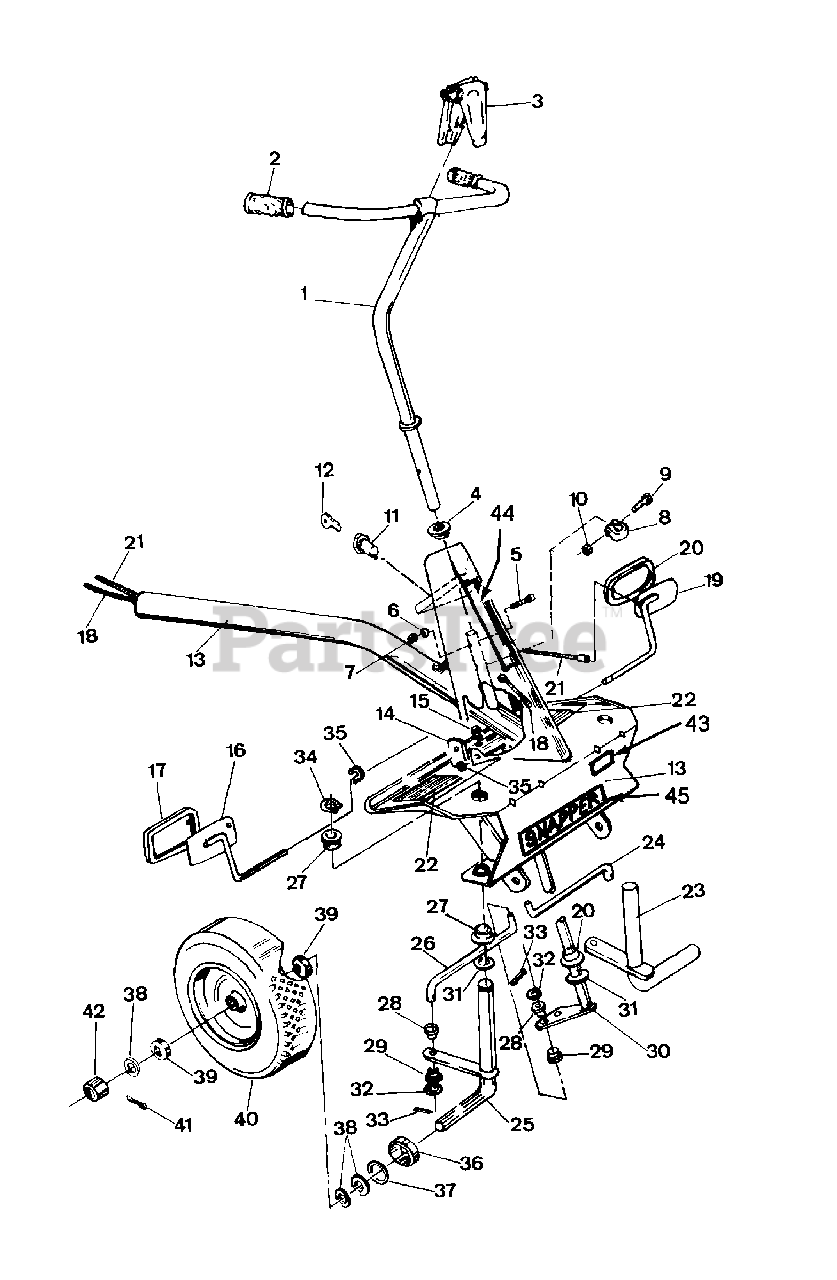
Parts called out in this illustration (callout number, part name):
1	HANDLE, Steering
2	GRIP, Steering Handle
3	COVER, Handle Center
4	BUSHING, Nylon
5	BOLT, Tapered Head
6	LOCKWASHER, 1/4 Int. Tooth
7	NUT, 1/4-28 Hex
8	CLAMP, (Handle Retaining)
9	CARRIAGE BOLT, 5/16-18 x 1-1/2"
10	NUT, 5/16-18 Hex
11	SWITCH, Ignition
12	KEY, Ignition Switch (Pair)
13	AXLE, Front (Structure)
14	MOUNT, Auxiliary Brake Pedal
15	SELF-TAP SCREW, 5/16-18 x 5/8"
16	PEDAL, Auxiliary Brake
17	PAD, Auxiliary Brake Pedal
18	CABLE, Auxiliary Brake (Orange w/13314 Belt)
19	PEDAL, Clutch/Brake
20	PAD, Clutch/Brake Pedal
21	CABLE, Clutch/Brake
22	PAD, Foot
23	King Pin, L.H.
24	TIE-Rod, Left hand
25	King Pin, R.H.
26	TIE-ROD, Right Hand
27	BEARING
28	BEARING, Half
29	BEARING, Half
30	SHAFT, Steering
31	WASHER, 5/8 Flat
32	WASHER, 3/8 SAE
33	COTTER-PIN, 5-32 x 3/4"
34	RING, Retaining
35	RING, Retaining
36	CAP, Dust
37	WASHER, Felt
38	WASHER, Spacer
39	BEARING, Ball
40	ASSEMBLY, Tire & Rim
41	COTTER-PIN, 5/32 x 1"
42	HUB-CAP
43	DECAL, Battery Warning
44	DECAL, Comet
45	DECAL, Snapper
